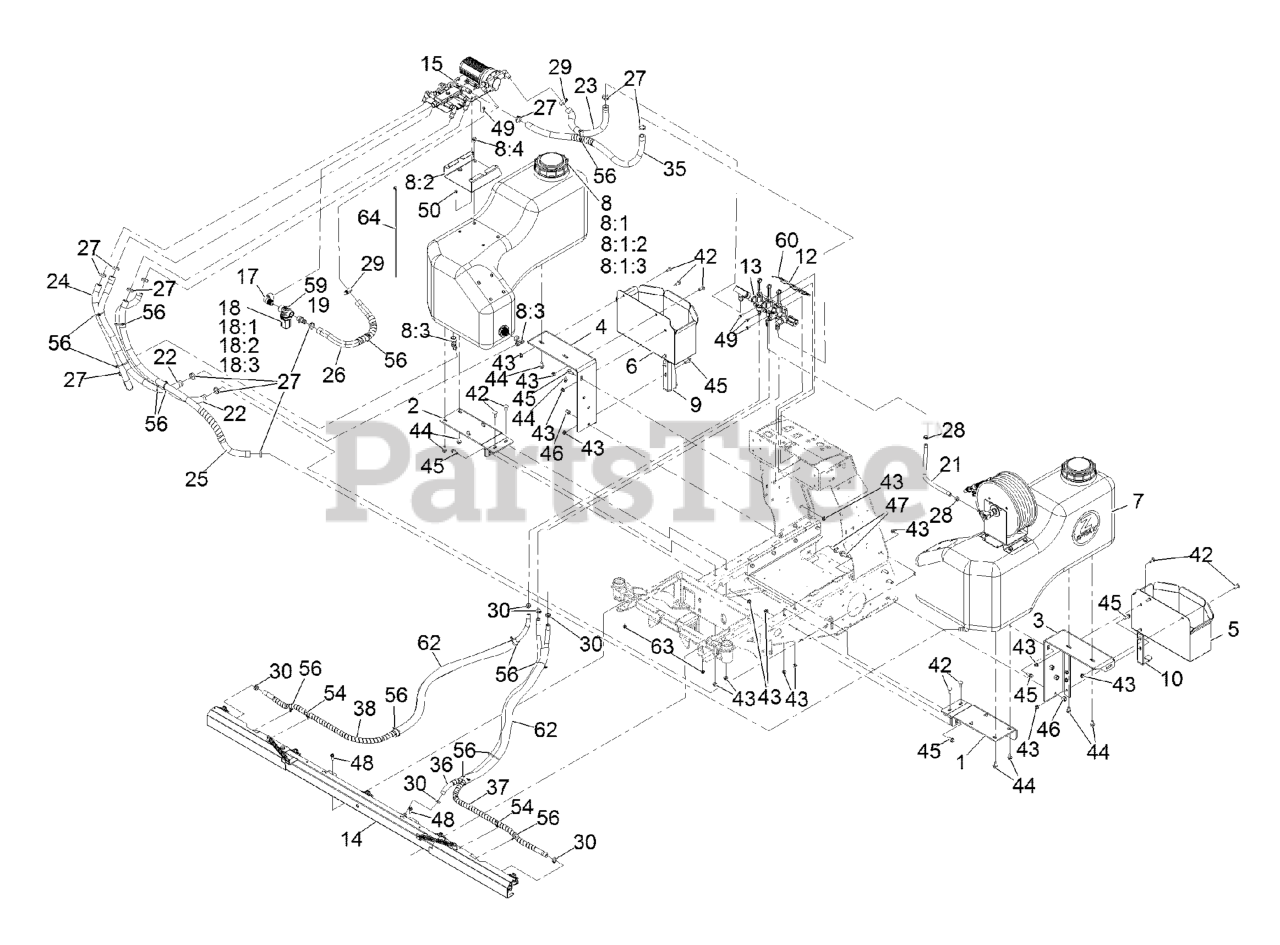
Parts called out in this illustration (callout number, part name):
1	Mount-Tank, LH Wing
2	Mount-Tank, RH Wing
3	Mount-Box, Lt Fert
4	Mount-Box, Rt Fert
5	Box-Fert, Lt
6	Box-Fert, Rt
7	ASM-Tank, Hose Reel
8	ASM-Tank, Rt
8:1	ASM-Tank, Rt
8:1:2	CAP-TANK, SPRAY
8:1:3	FITTING-BULKHEAD
8:2	PLATFORM, LIQUID VALVE MO
8:3	FITTING-ELBOW, 90
8:4	Screw-HHF
9	Bracket-Anti-Tip, Rt
10	Bracket-Anti-Tip, Lt
12	BRACKET-MANIFOLD
13	ASM-Manifold
14	ASM-Boom
15	ASM, Liquid Valve
17	ELBOW-90DEG
18	STRAINER-INLINE
18:1	BOWL-STRAINER
18:2	GASKET-HEAD, LINE STRAINE
18:3	Screen-Strainer, 50 Mesh
19	HOSEBARB
21	Hose-Spray
22	Hose-Spray
23	Hose-Spray
24	Hose-Spray
25	Hose-Spray, Wrapped
26	Hose-Spray, Wrapped
27	Clamp-Oetiker, 167
28	CLAMP-OETIKER, 167
29	CLAMP-HOSE
30	CLAMP-OETIKER, 167
35	Hose-Spray, Wrapped
36	HOSE-SPRAY, WRAPPED
37	HOSE-SPRAY, WRAPPED
38	HOSE-SPRAY, WRAPPED
42	SCREW-CARR
43	Nut-Hex Flange
44	SCREW-HHF
45	SCREW-HHF
46	Nut,1/2-13,NYL INS,ST/ST,18-8
47	SCREW-HHF
48	SCREW-HHF
49	Screw-HHF
50	Nut-Hex Flange
54	CLIP-TIE
56	TIE-CABLE
59	DECAL-CAP, STRAINER
60	Decal-Valve, Boom
62	Guard-Mesh
63	Nut-Hex Flange
64	TIE-CABLE
